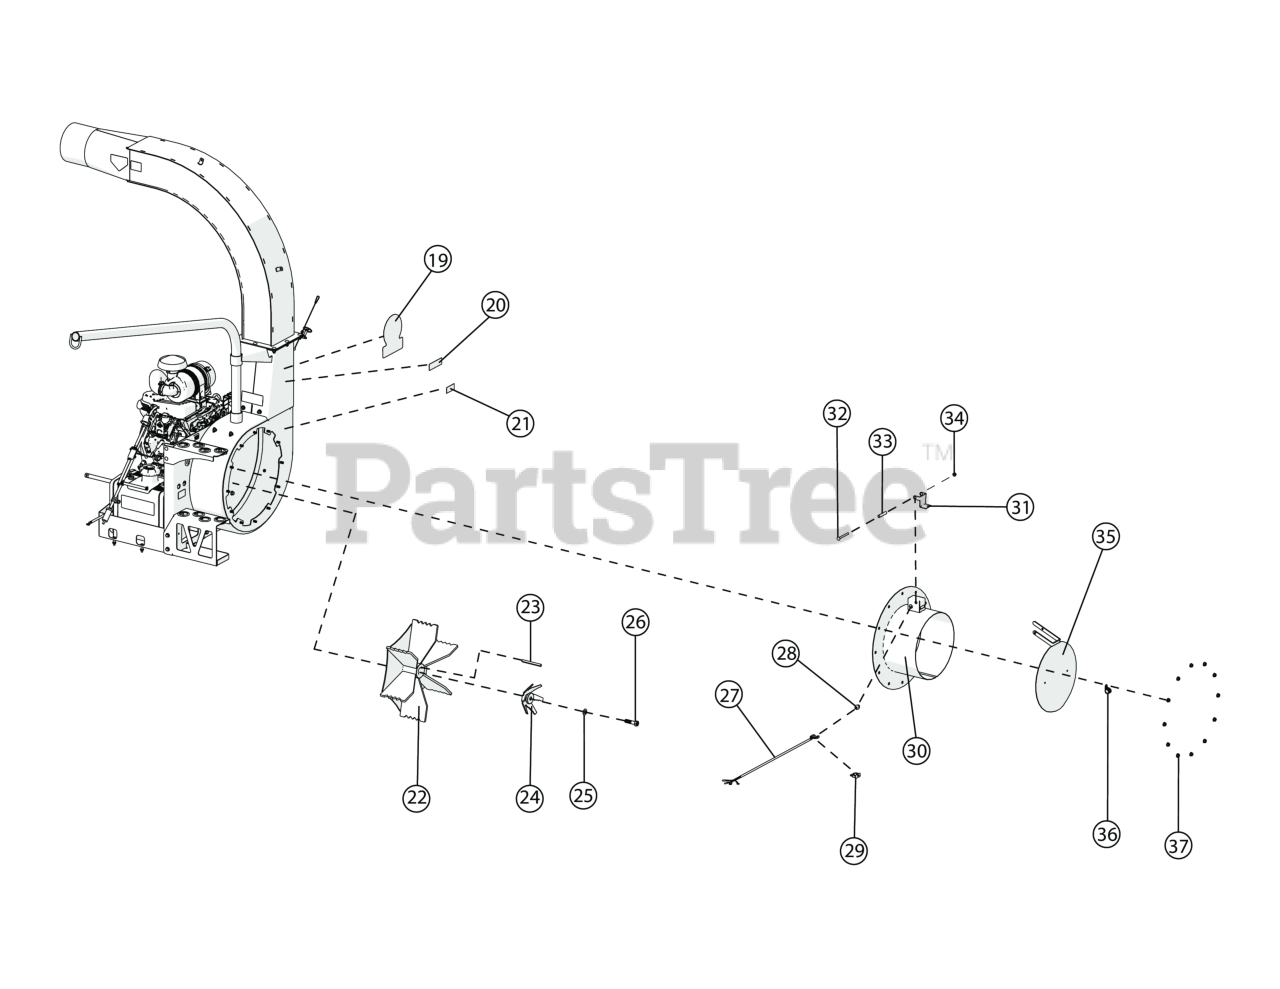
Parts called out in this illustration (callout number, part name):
19	LABEL, DL SERIES
20	LABEL DL PIRANHA
21	LABEL, WARNING LINER DL
22	IMPELLER WA 20.00" X 1.4375" LOADER DL29
23	KEY 3/8" SQ. X 4.50"
24	PIRANHA BLADE WA DL35
25	WSHR-STL, BLV, .642" X 1.25" X .089" MZ
26	SCREWCAP 5/8"-18 X 3.00" ZP GR8
27	HARNESS, WIRING DL
28	STRAIN RELIEF
29	SWITCH, SAFETY INTERLOCK
30	INTAKE HOUSING WA 14" LOADER DL35
31	LEVER HOSE SWITCH
32	BOLT CARRIAGE 5/16"-18 X 3 1/2" ZP
33	SPACER 3/8" X 2 1/2"
34	NUT-HEX-NYLK, FLG .3125-18 ZP
35	FLAPPER WA 14" INTAKE DL35
36	CLAMP ROUTING FUEL LINE
37	NUT WASHER FACE
